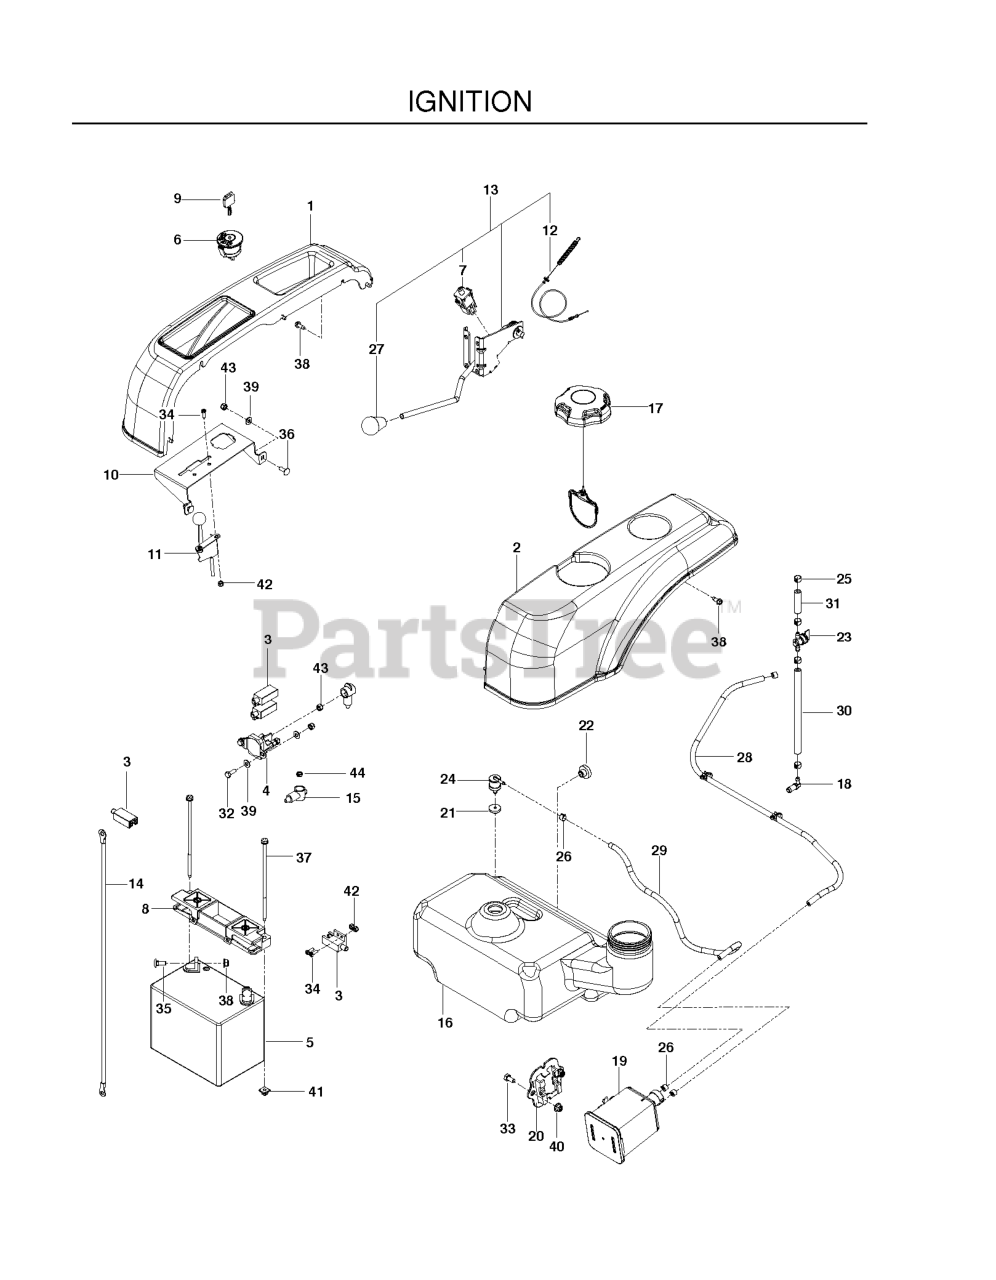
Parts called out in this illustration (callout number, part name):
1	FENDER, RZ 30/38 RT
2	FENDER, RZ 30/38 LT
3	SWITCH, INTERLOCK
5	BATTERY, 12 V 330 AMP
6	RP IGNITION SWITCH
7	SWITCH INTERLOOK PUSH-IN
8	BATTERY HOLD DOWN
9	KEY
10	MOUNT, CONTROLS, BLK
11	CABLE, THROTTLE
12	CABLE.CLUTCH.38".SERVICE
13	ASM, CLUTCH ENGAGE W/CABLE
14	BATTERY CABLE, NEGATIVE
15	TERMINAL COVER-SM
16	RP.TANK, FUEL EPA
17	CAP, FUEL
18	STEM, FUEL TANK
19	CANNISTER, CARBON
20	BRACKET, CANISTER
21	GROMMET, CHECK VALVE
22	RUBBER GROMMET
23	FUEL VALVE
24	VALVE.FUEL.CHECK
25	HOSE CLAMP
26	CLAMP, HOSE
27	KNOB - SHIFT
28	FUEL LINE 33"
29	HOSE, FUEL, 3/16" X 20"
30	HOSE 1/4 X 8
31	HOSE 1/4 X 2"
32	HCS 1/4C X 3/4 HCS
33	HCS 5/16-18 X 5/8 GR 5 ZD
34	SCREW #10-24 X 5/8
35	BOLT 5/16C X 3/4" CARRIAGE
36	RHSNB 1/4C X 3/4
37	BOLT - 1/4-20 X 7.5
38	SCREW 1/4 X 5/8
39	WASHER 1/4 SAE
40	5/16-18 NYLOC FLANGE NUT
41	PUSH NUT-NYLON
42	NUT 10-24 NYLOC
43	NUT.1/4-20.HEX.NYLOC.ZD
44	JAM NUT 1/4C (2 2 PW01)
